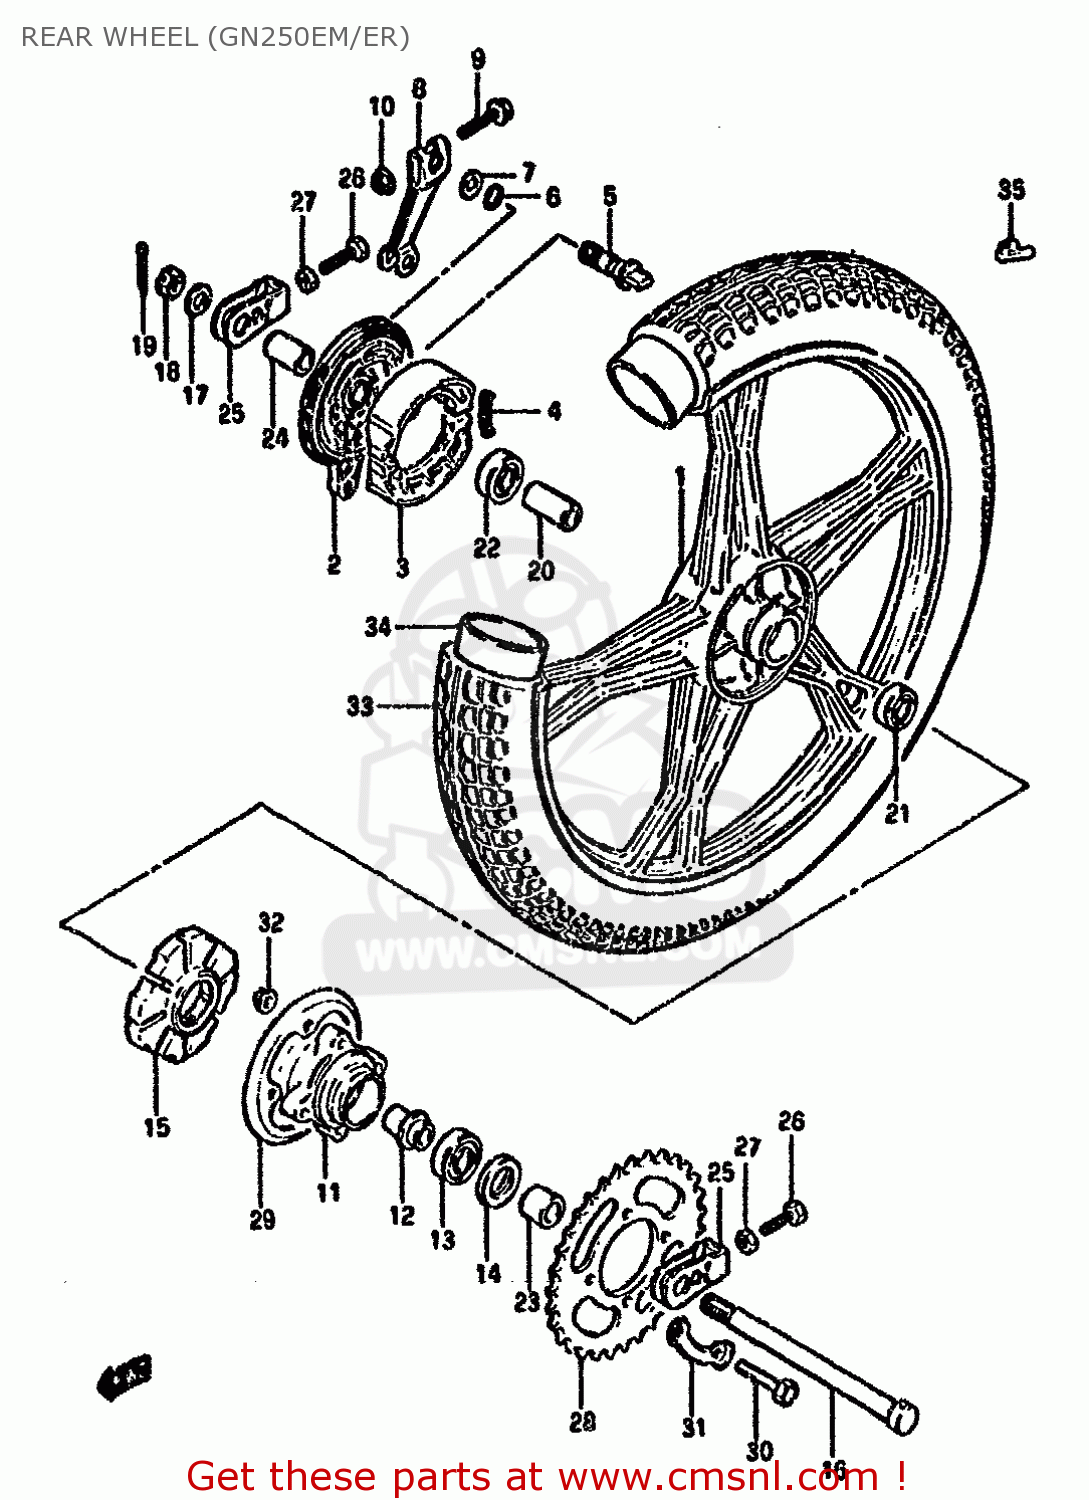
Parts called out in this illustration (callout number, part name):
1	WHEEL,RR(2.15X10)
2	PANEL,RR BRAKE ANCHOR
3	SHOE,BRAKE
4	SPRING(L:34)
5	CAM,FRONT BRAKE
6	O-RING (D:2.4 ID:13.8)
7	WASHER (14.5X22X1.6)
8	LEVER,RR BRAKE CAM
9	BOLT
10	NUT
11	DRUM,RR SPROCKET MOUNTING
12	RETAINER,RR SPROCKET DRUM
13	BEARING(20X47X14)
14	SEAL,OIL(28X47X7)
15	ABSORBER,RR HUB SHOCK
16	AXLE,REAR
17	WASHER
18	NUT
19	COTTER PIN
20	SPACER(15.3X21.7X63)
21	BEARING
22	BEARING
23	SPACER(15X28X24.8)
24	SPACER(15X22X46.8)
25	ADJUSTER,CHAIN
26	BOLT
27	NUT
28	SPROCKET,REAR
29	GUIDE,RR SPROCKET CHAIN
30	BOLT 10X40
31	WASHER
32	NUT
33	TIRE
34	NUT
35	BALANCER,WHEEL
36	TUBE ASSY,WHEEL,INNER 4.60-16
37	PROTECTOR,WHL INR TUBE
38	RIM,RR WHEEL(215X16)
39	SPOKE SET,REAR WHEEL
40	BALANCER,WHEEL (B)
